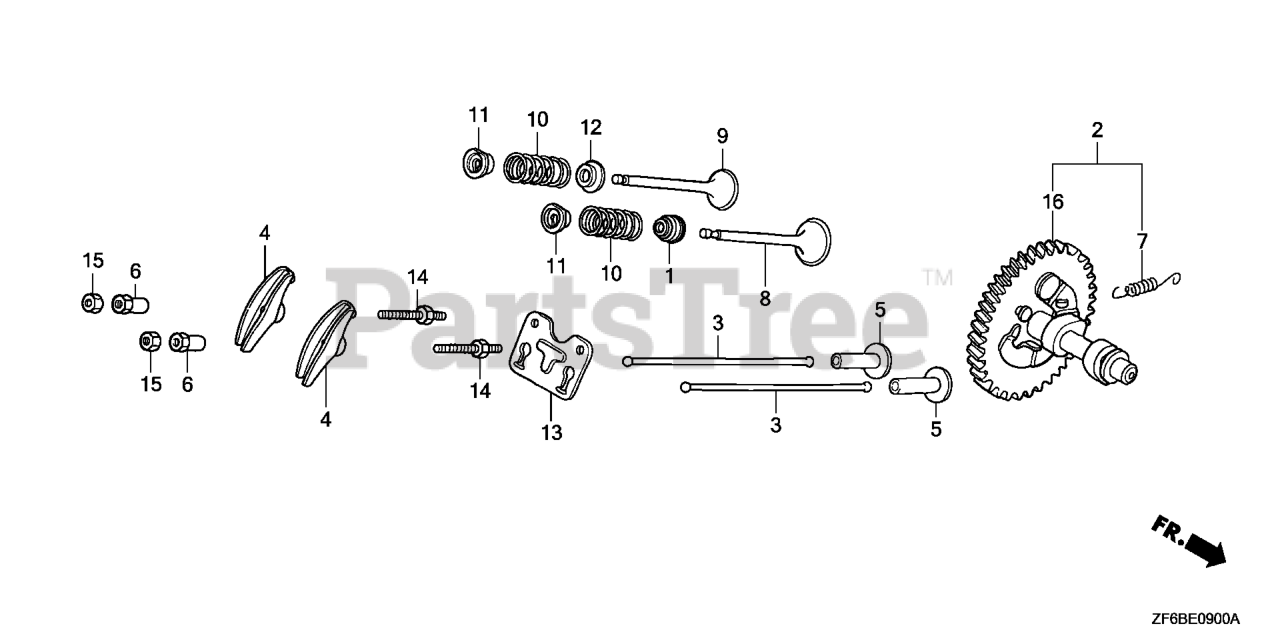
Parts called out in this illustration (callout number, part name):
1	SEAL, VALVE STEM
2	CAMSHAFT (STD)
2	CAMSHAFT COMP (STD)
3	ROD, PUSH
4	ARM, VALVE ROCKER
5	LIFTER, VALVE
6	PIVOT, ROCKER ARM
7	SPRING, WEIGHT RETURN
8	VALVE, IN.
9	VALVE, EX.
10	SPRING, VALVE
11	RETAINER, IN. VALVE SPRING (EXHAUST SIDE)
12	SEAT, VALVE SPRING
13	PLATE, PUSH ROD GUIDE
14	BOLT, PIVOT (8MM)
15	NUT, PIVOT ADJ.
16	CAMSHAFT (STD)
16	CAMSHAFT COMP (STD)
